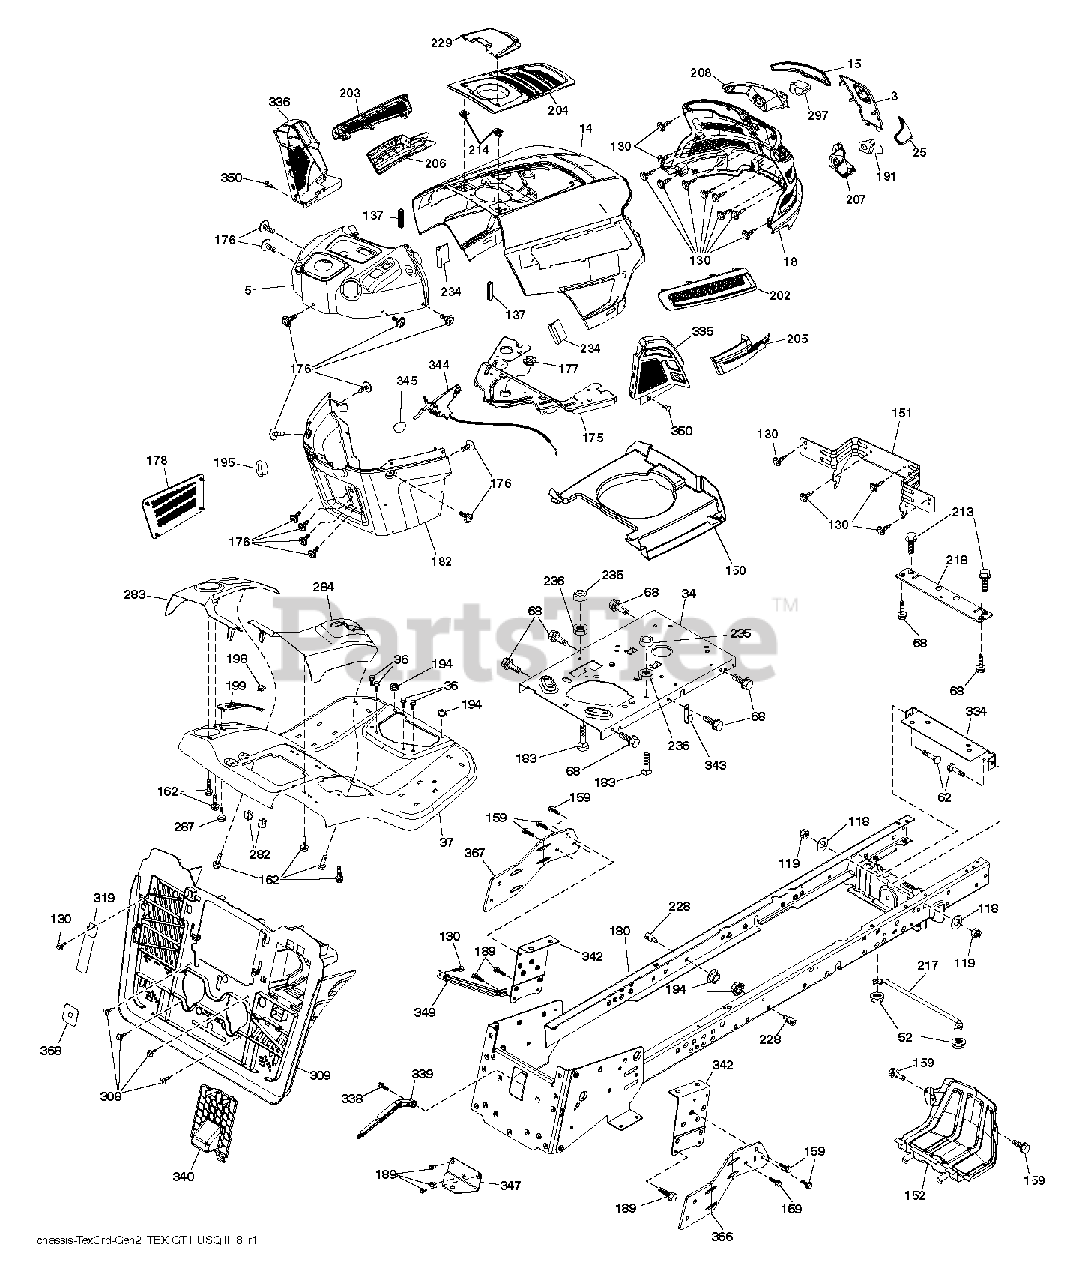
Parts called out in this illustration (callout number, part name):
3	APPLIQUE.SUBASM.GT.HUSQ.II
14	HOOD.ASM.HUSQVARNA.GT.TEX.ORAN
15	LENS.HEADLIGHT.LH.GTII.2011
18	GRILLE.SUBASM.GT.HUSQ.II
25	LENS.HEADLIGHT.RH.GTII.2011
34	PLATE.ENGINE.WELDED.CHASSIS
36	SCREW 5/16"
37	FENDER.TEX.SRD.CRD.BASE
52	LOCKNUT
62	BOLT D
68	SCREW LT
118	WASHER
130	SCREW.#10 X 0.750.BOS
137	BUMPER DASH
150	AIR DUCT.GTV2(1.66"RING HEIGHT
151	BRACKET.PIVOT.HOOD.GT.HUSQ.II
152	SHIELD.BROWNING.PNT.GT.V2
159	SCREW, 3/8-16X3/4
162	SCREW.HI-LO.CONSOLE
175	PLATE.CROSSMEMBER.HUSQ
176	SCREW.#10-24X5/8.RN.QU
177	BUSHING, STEERING
178	CARGO.ASM.NET.TXGT.W/C
182	DASH DASH LOWER
183	BOLT.5/16-18X1-1/4 FULL THD
189	SCREW
191	INSERT.REFLECTIVE.RH.HUSQ.GTII
194	NUT LOCK HEX FLANGE 5/16-18
195	PLUG.HOLE.DASH.LOWER.12V.BLK
198	INDICATOR.DECK.LIFT.RED
199	PLATE DECK LIFT
202	VENT.SIDE.RH.GT.HUSQ.II.
203	VENT.SIDE.LH.GT.HUSQ.II.498
204	VENT.TOP.EXTERNAL.FILL.GT2.GRE
205	SIDE.TRIM.RH.GT.HUSQ.II
206	SIDE.TRIM.LH.GT.HUSQ.II.GRAY
207	BEZEL LIGHT.RH.GT.II.MYLAR
208	BEZEL LIGHT.LH.GT.II.MYLAR
213	BOLT
214	CLIP.RETAINER.TINNER.
217	ROD.PIVOT.HOOD
218	X-PIECE.HOOD.STOP.NON/
228	STUD.FASTNER.W/ANTI-ROTATE
229	LID.EXT.FILL.GT.HUSQ2.BLACK
234	BUMPER.HOOD.TEX.HUSQVARNA
235	SPACER FENDER
236	NUT.CENTERLOCK.5/16-
282	CLIP.RETAINER.CONSOLE.LT.HUSQ
283	CONSOLE.DECKLIFT.CRDII.498
284	CONSOLE.PEDAL.HYDRO
287	SCREW 1/4X20
297	INSERT.REFLECTIVE.LH.HUSQ.GTII
308	BOLT, 5/16-18 X 1 3/4
309	BACKPLATE.SUBASM.SERV.TEX.CRD.
319	LEVER.BAGGER.TEX.CRD.GEN.BLACK
334	BRACKET.ENGINE
335	COVER.LOWER.DASH.RH.BLACK
336	COVER-LH.LOWER.DASH.GT2.BLACK
338	BOLT BOLT SHOULDER
339	LEVER LEVER BAGGER
340	BATTERY.DOOR.TEX.CRD.GEN.2,1
342	SUPPORT SUPPORT FENDER
343	CLIP CLIP
344	CONTROL.EZ.MULCH.TEX/CRD
345	RP KNOB.OVAL.TAPERED.3/8-16BLK
347	HITCH TOW
349	BRACKET.SUPPORT.LRVB/CRD
350	CLIP.X-MAS.TREE
366	BRACKET.RH.FRONT.BAGGER.BLACK
367	BRACKET.LH.FRONT.BAGGER.BLACK
368	FULL.LEVER.BAGGER.TEX.CRD
